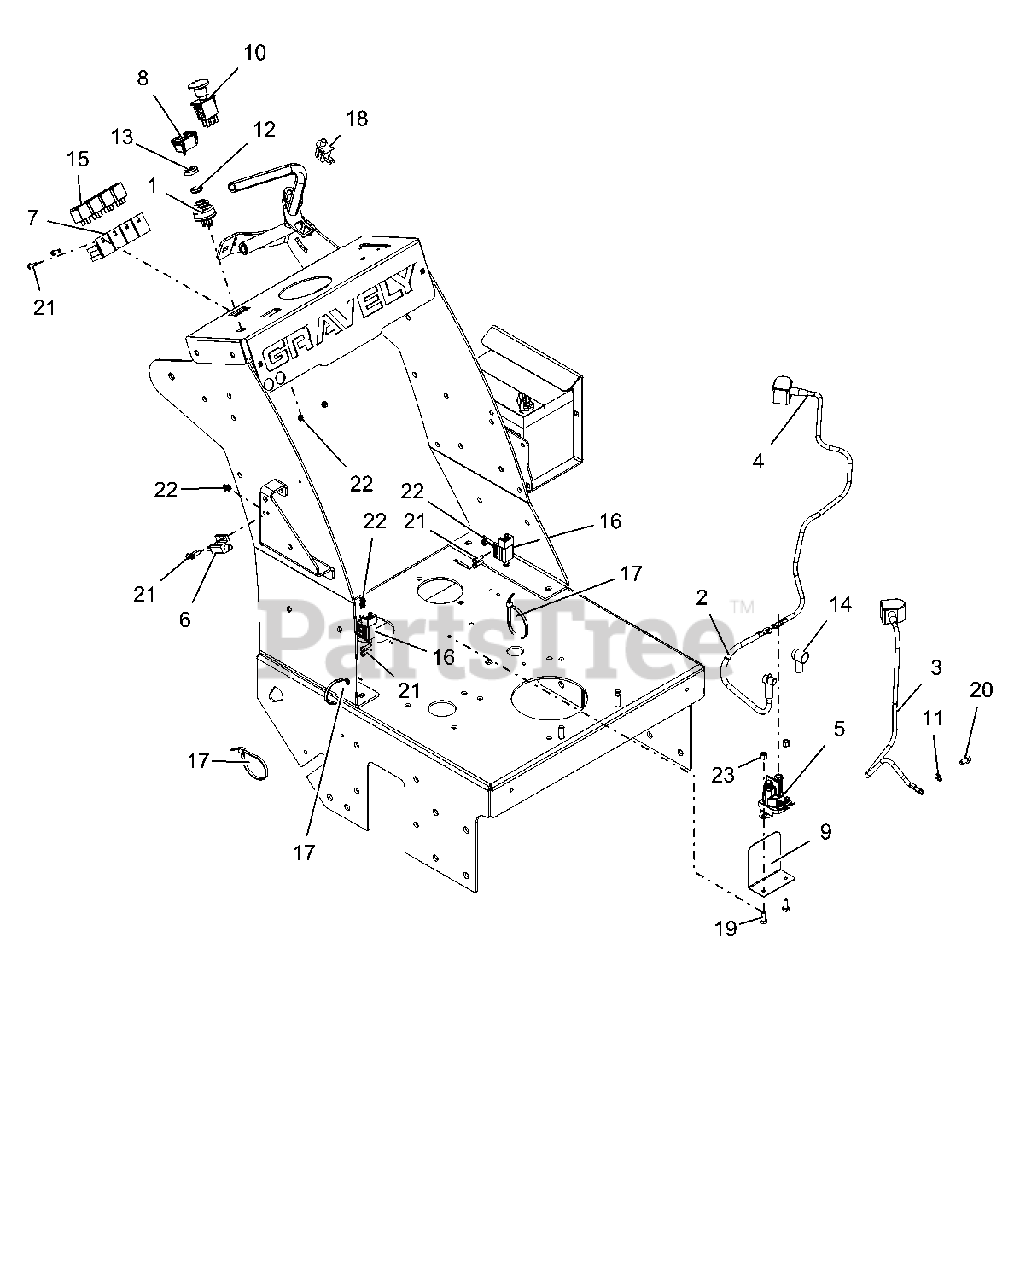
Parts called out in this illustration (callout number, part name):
1	SWITCH, KEY - 3 POSITION
2	CABLE, STARTER 12"
3	CABLE, BATTERY GROUND 25"
4	CABLE, BATTERY POSITIVE 25"
5	SOLENOID REV D
6	SWITCH- DOUBLE POLE N.O./N.O.
7	HARNESS, ELEC START MY2011FSWLK
8	METER, HOUR SMART SENSE W/O SV
9	COVER, SOLENOID-BLACK
10	SWITCH, CLUTCH (WITH GRAPHIC)
11	WSHR-LK-EXT .326X.599X.031 YWZC REV
12	NUT-PANEL .625-32 GRECO REV
13	CAP, IGNITION SWITCH
14	BOOT, EYELET TERMINAL
15	RELAY, ISO MINI ELEC.
16	SWITCH, PLUNGER DP-N.O.-N.C.
17	CABLE TIE, .19 X 14.4
18	SWITCH, SEAT OVERIDE (N.O.)
19	BLT-HEX .25-20X.75 GR5 YWZC
20	@BLT-HEX M8 X 1.25X14 YWZC
21	@SCR-MCH 10-24X.75 HWH YWZC
22	NUT-KEPS 10-24
23	NUT-LK-NYL .250-20 YWZC
